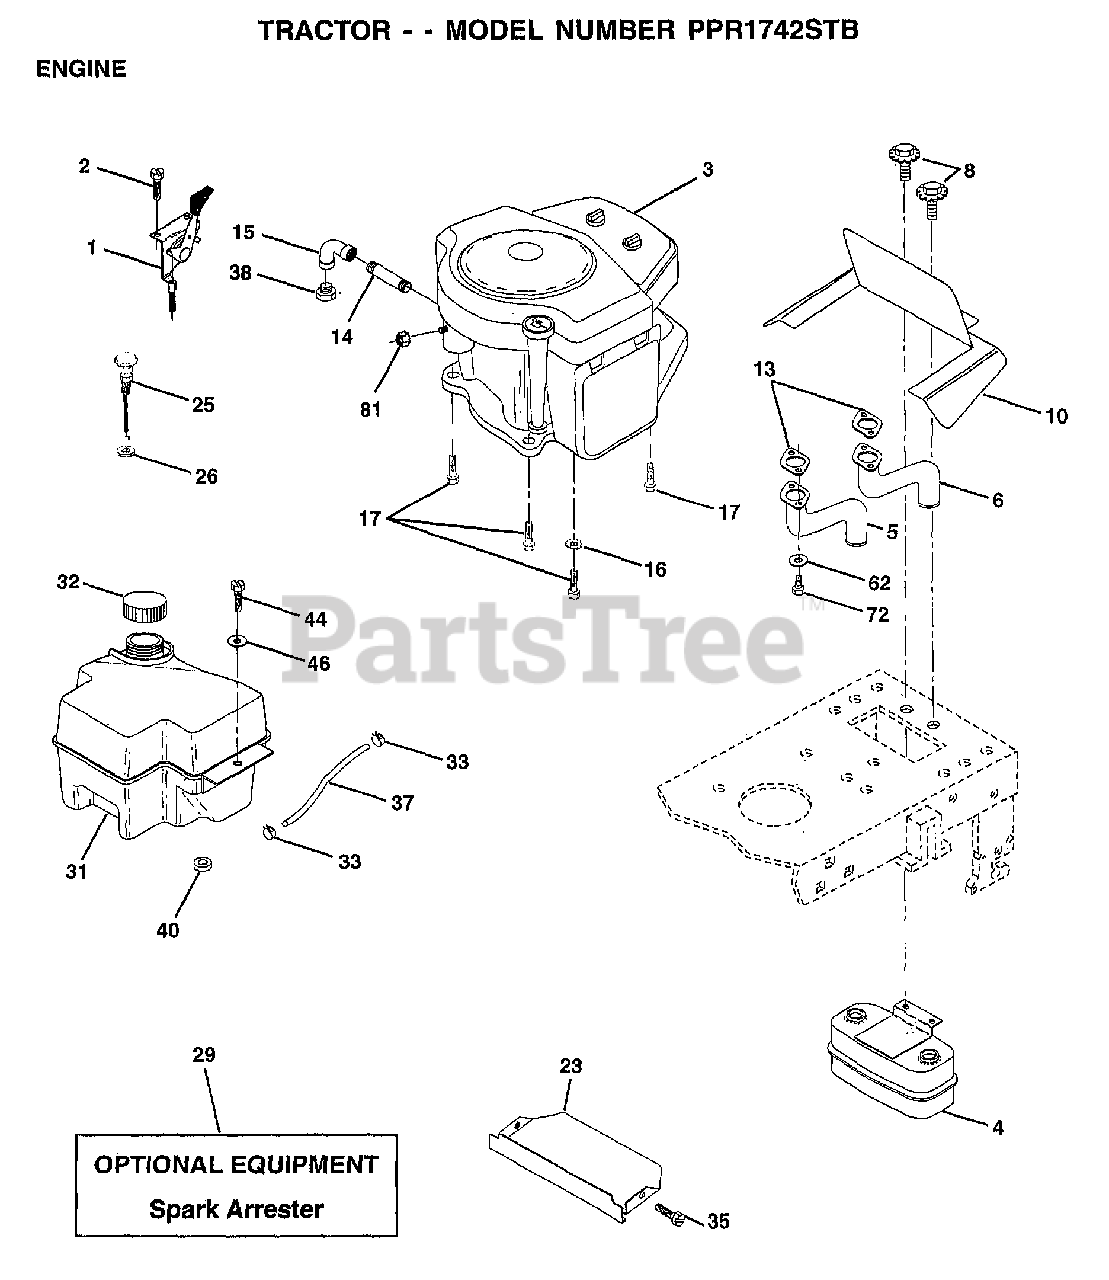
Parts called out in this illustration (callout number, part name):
1	CONTROL THROT. LH
2	SCREW LT
4	MUFFLER.TW.LOTONE
5	TUBE MANIFOLD LH
6	TUBE MANIFOLD RH
8	BOLT.5/16-18.UNC
10	SHIELD.BROWNING
14	PIPE NIPPLE LT
15	ELBOW
16	LOCKWASHER
17	SCREW LT
23	SHIELD.BRN/DBR.GD
25	CONTROL.CHOKE.37
26	"NUT,KEPS 3/8-24IM"
31	TANK.FUEL.FRONT.
32	CAP ASM FUEL
33	HOSE CLAMP
35	SCREW
37	LINE FUEL
44	SCREW HEX CRT
46	WASHER
62	LOCKWASHER
72	SCREW
81	NUT
